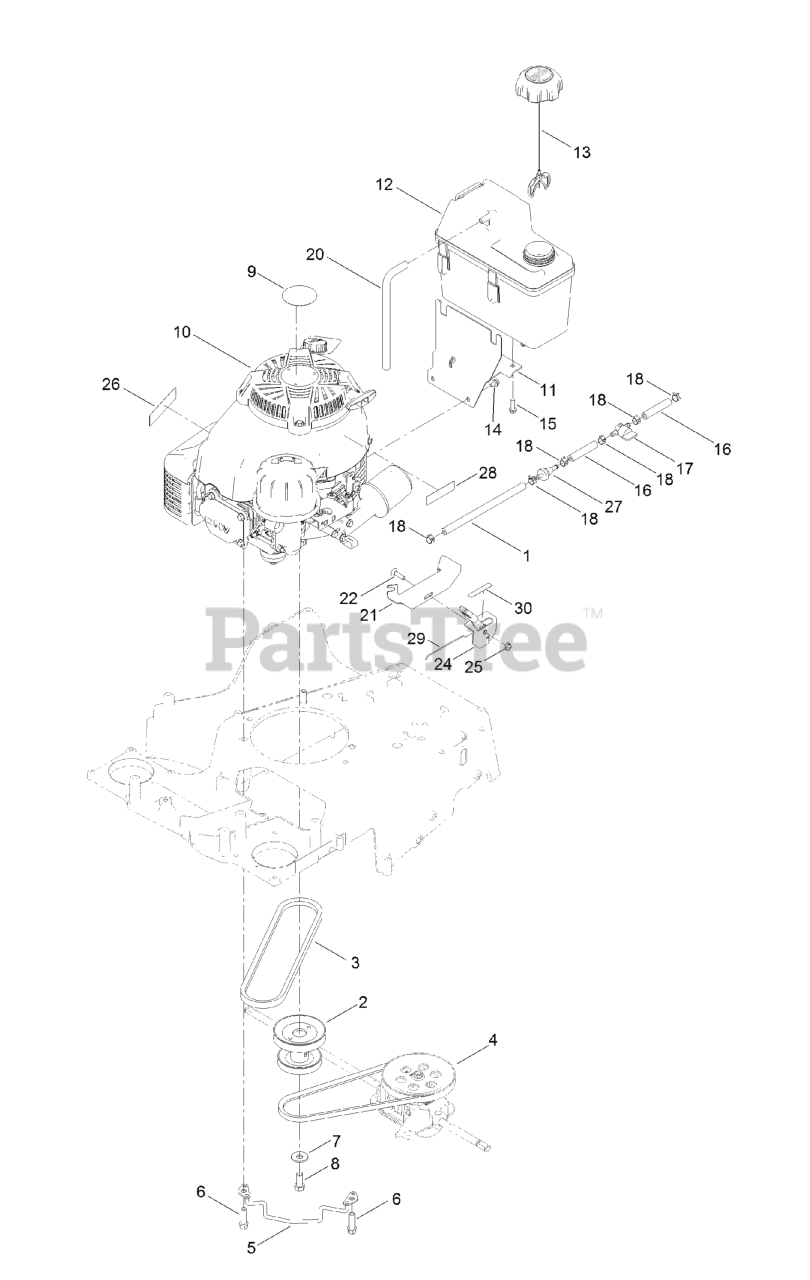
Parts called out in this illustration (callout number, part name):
1	HOSE-FUEL
2	PULLEY-ENGINE
4	BELT
5	GUIDE-BELT
6	SCREW-TAPTITE
7	WASHER-BELLEVILLE
8	SCREW-HH
11	MOUNT-TANK
12	TANK-FUEL
13	CAP-FUEL
14	SCREW-HWH
15	SCREW-HWH
16	HOSE-FUEL
17	VALVE-FUEL
18	CLAMP-HOSE
20	HOSE-VENT, CANISTER
21	BRACKET-MOUNT, THROTTLE
22	SCREW-CARR
24	CONTROL-THROTTLE
26	DECAL-ARRESTOR, SPARK
27	FILTER-FUEL
28	DECAL-WARNING, ENGINE
29	WIRE-CONTROL
30	DECAL-THROTTLE, CHOKE
